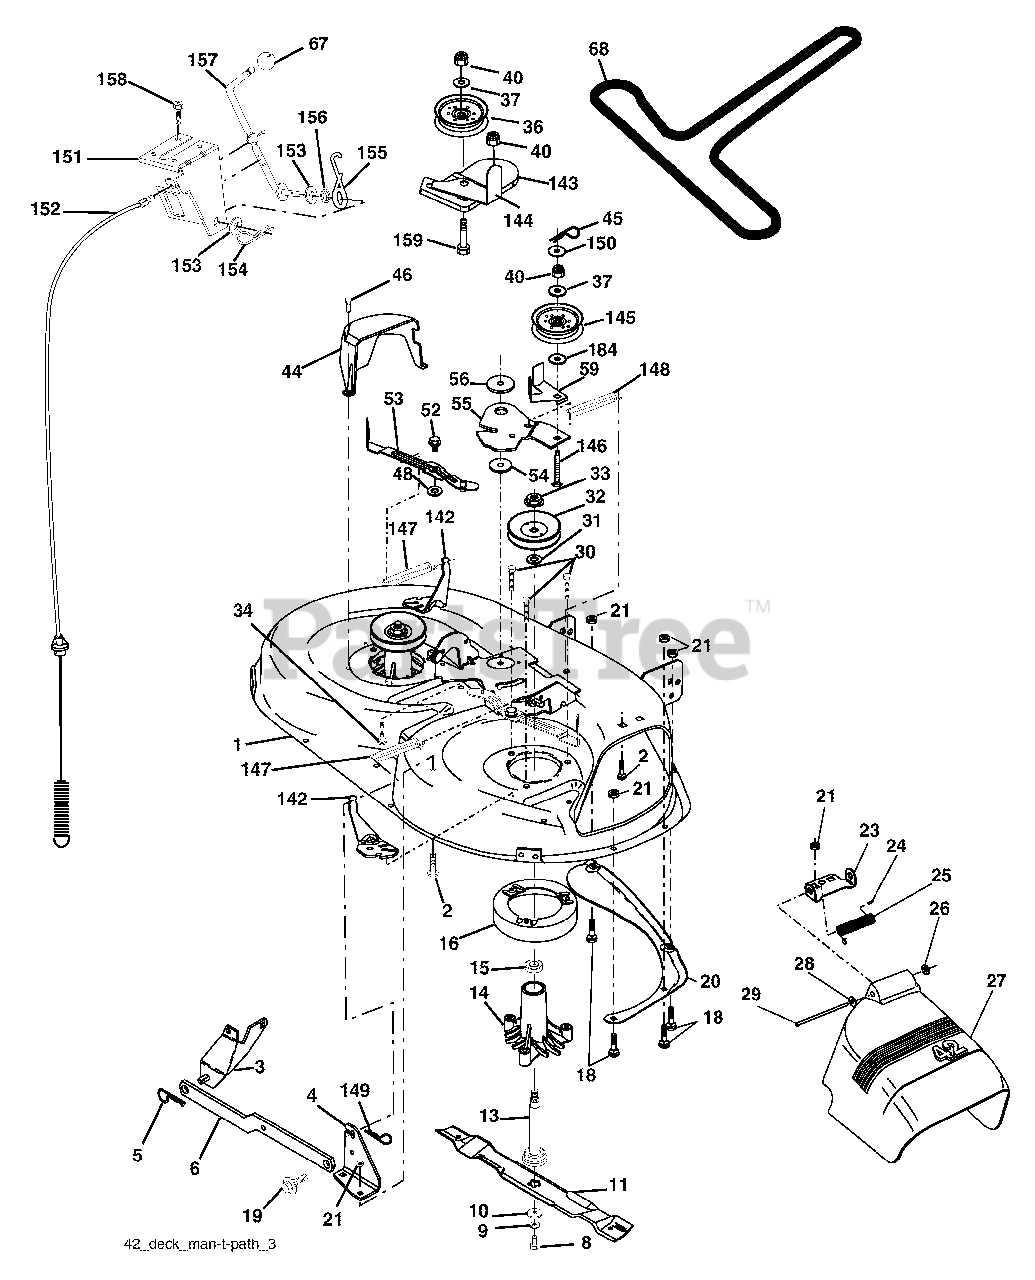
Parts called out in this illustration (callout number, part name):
1	Mower Deck Assembly, 42"
2	Bolt
3	Bracket Asm Fr. Sway Bar 3/42
4	Bracket Asm Deck 42" Sway Bar
5	Retainer Spring
6	Bar Sway Deck
8	Bolt 3/8-24 x 25 Grade 8 patched
9	Washer, Lock
10	Washer, Hardened
11	Blade, 42" Mulching Std
11	Blade, 42" Mulching Premium
11	Blade, 42" Hi-Lift
13	Shaft Assembly, Mandrel, Vented
14	Housing, Mandrel, Vented
15	Bearing, Ball, Mandrel
16	Stripper, Mandrel Deck
18	Bolt, Carriage 5/16-18 x 5/8
19	Bolt, Shoulder
20	Baffle, Vortex
21	Nut
23	Bracket, Deflector Mower 42"
24	Cap, Sleeve 80 x 112 Blk Mower
25	Spring, Torsion, Deflector 2 52
26	Nut, Push Phos & Oil
27	Shield, Deflector 42" Blk
28	Washer 11/32 x 5/8 x 16 Ga.
29	Rod, Hinge 42" 6 75 W/G
30	Screw Thdrol Washer Head
31	Washer, Spacer Mower Vented
32	Pulley, Mandrel
33	Nut, Toplock 9/16 Flange
34	Bolt
36	Pulley, Idler, Flat
37	Washer 13/32 x 13/16 x 16 Ga.
40	Nut
44	Guard, Mandrel, LH
45	Retainer
46	Screw,
48	Washer, Hardened
52	Bolt, Shoulder 5/16-18 UNC
53	Arm Assembly, Pad, Brake
54	Washer, Hardened
55	Arm, Idler
56	Spacer, Retainer
59	Guard TUV Idler
67	Knob
68	V-Belt, 42" Mower
142	Arm Spring Brake Mower
143	Bracket Arm Idler 42"
144	Keeper Belt 42" Clutch Cable
145	Pulley Idler Flat
146	Bolt Carriage Idler
147	Spring Extension
148	Spring Return Idler
149	Retainer Spring Yellow
150	Washer 9/32 x 3/4 x 16 Ga.
151	Bracket Clutch Cable
152	Clutch Cable 42"
153	Washer Flat 3/8" Type B
154	Spring Retainer
155	Spring Retention LVR CLTCH CAB
156	Spacer Clutch Cable
157	Rod Clutch Cable 3/8"
158	Screw Hex Thd Cut 1/4-20 x 1/2
159	Bolt Rdhd Sqn 3/8-16 UNC x 1-3/4
184	Washer 13/32 x 7/8 x 10 Ga.
